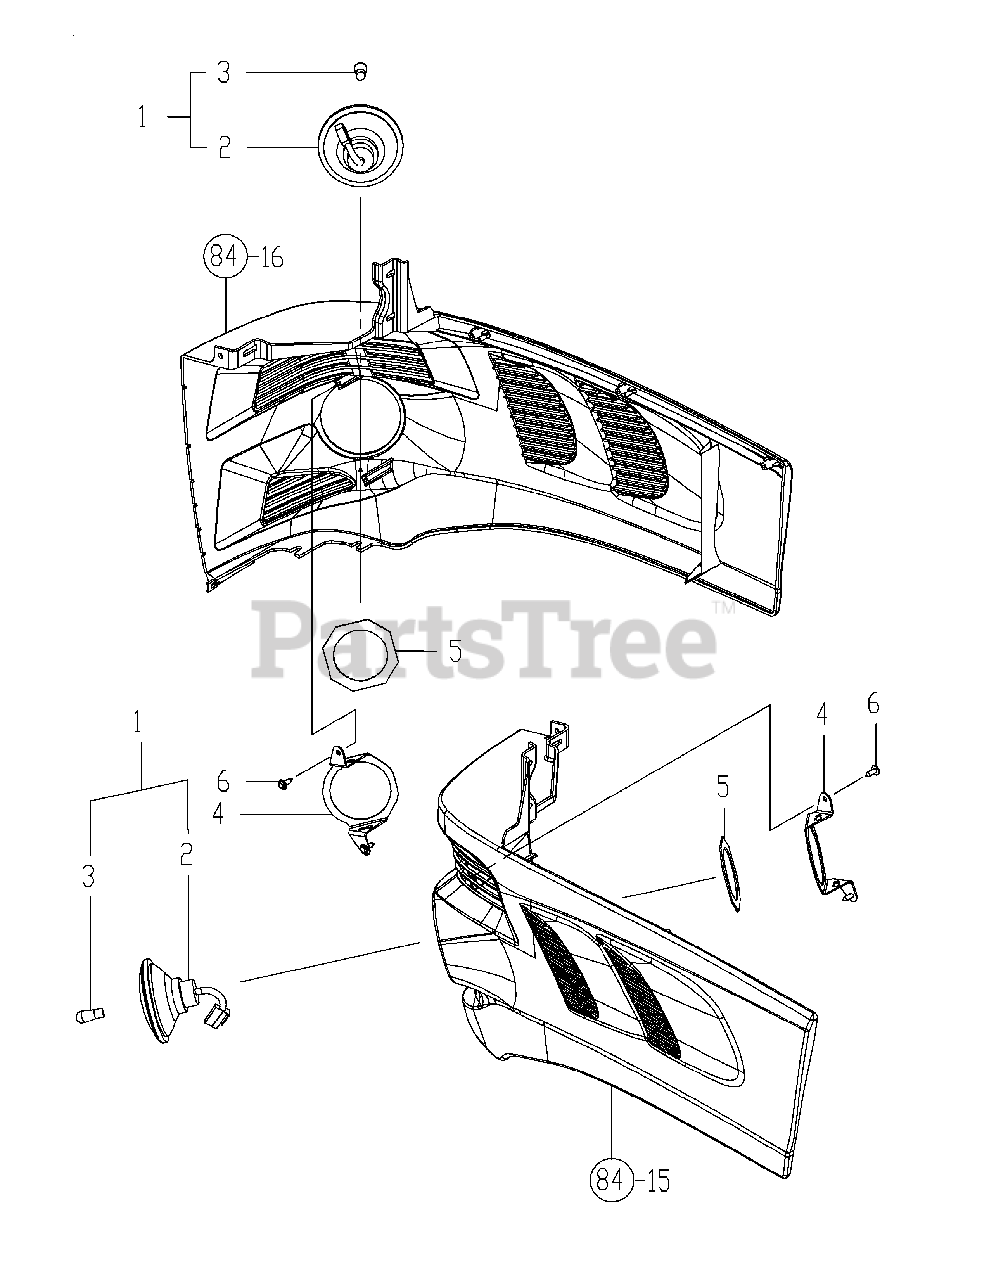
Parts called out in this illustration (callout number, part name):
1	LAMP ASSY, SIDE
2	CASE ASSY, SIDE LAMP
5	RUBBER, SIDE LAMP
